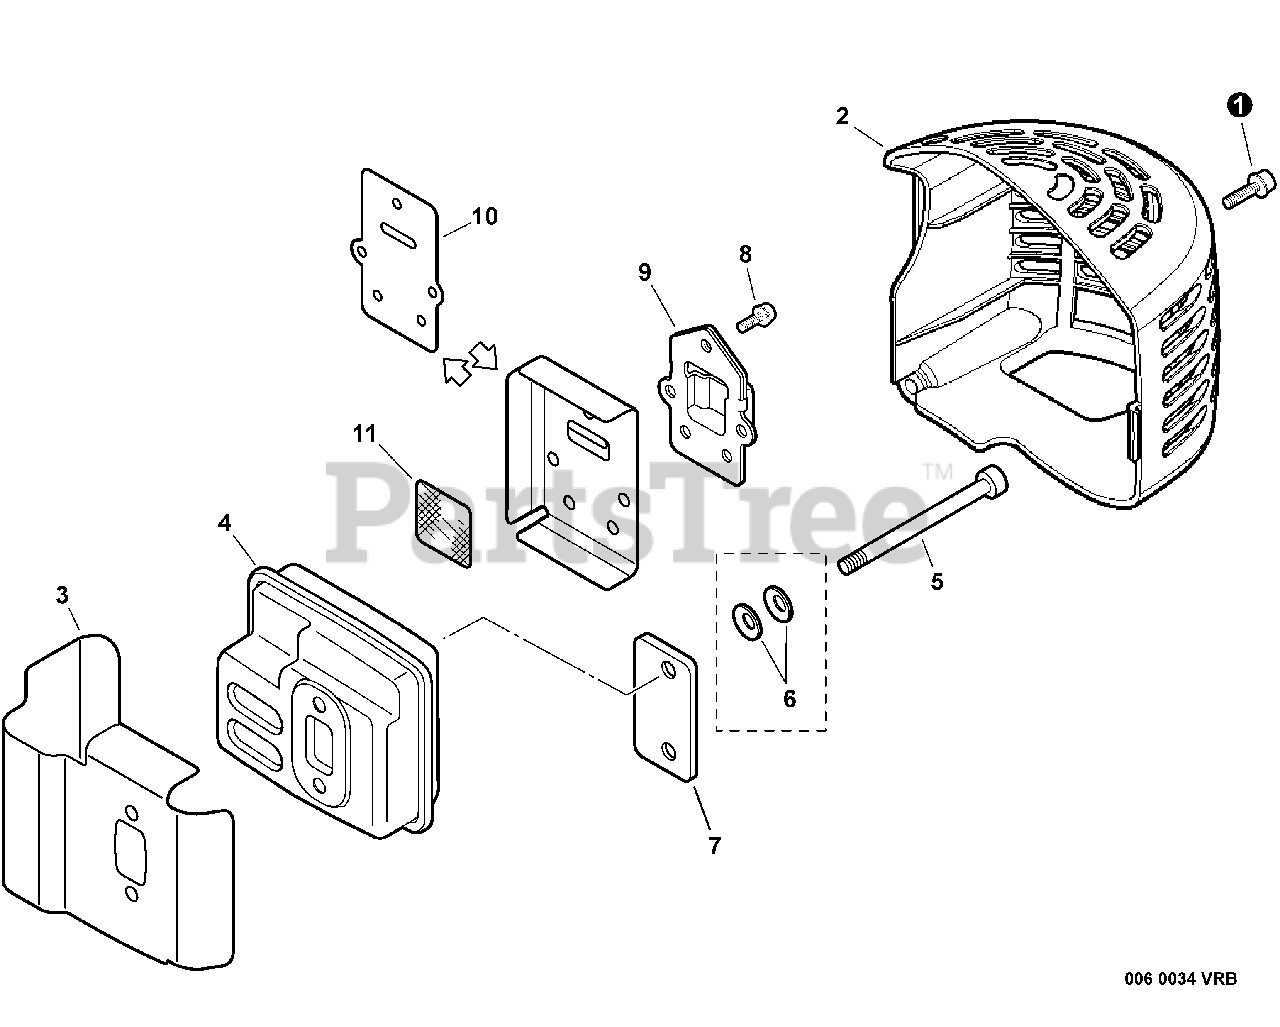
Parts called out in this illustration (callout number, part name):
1	SCREW - 5X16
2	COVER, EXHAUST
3	SHIELD, EXHAUST
4	MUFFLER
5	SCREW - 5X55
6	WASHER - CONICAL
8	SCREW - 4X12
9	GUIDE, EXHAUST
10	GASKET, EXHAUST
11	SCREEN, SPARK ARRESTOR
